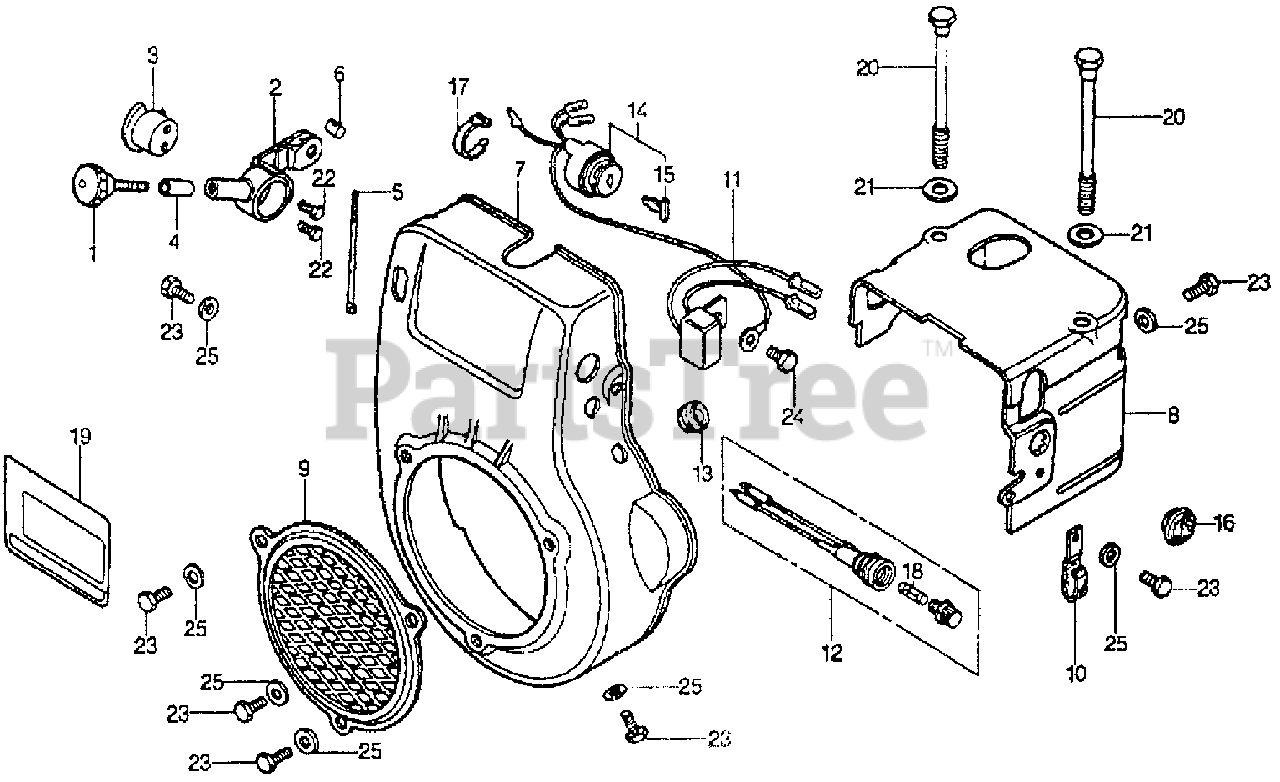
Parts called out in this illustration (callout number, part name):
1	SCREW, GOVERNOR ADJUST (NOT AVAILABLE)
2	LEVER, CONTROL (NOT AVAILABLE)
3	SHAFT, CONTROL (NOT AVAILABLE)
4	BUSH, CONTROL (NOT AVAILABLE)
5	ROD, ADJUSTING
6	JOINT, ADJUSTING ROD (NOT AVAILABLE)
7	COVER, FAN *R8* (BRIGHT RED)
8	COVER, SIDE *R8* (BRIGHT RED)
9	PROTECTOR, FAN COVER *R8* (BRIGHT RED)
10	CLAMP, WIRE
11	DIODE
11	RECTIFIER, SILICON (NOT AVAILABLE)
12	HOLDER, FUSE
13	GROMMET, CABLE
14	SWITCH ASSY., COMBINATION
16	GROMMET, COVER (NOT AVAILABLE)
17	BAND, CABLE
18	FUSE (15A)
19	PLATE, DESCRIPTION (NOT AVAILABLE)
20	BOLT, HEX. (10X76)
21	WASHER, MAGNET FIXING
22	BOLT, HEX. (5X8)
23	BOLT, HEX. (6X12)
24	BOLT, HEX. (6X6)
25	WASHER, PLAIN (6MM)
